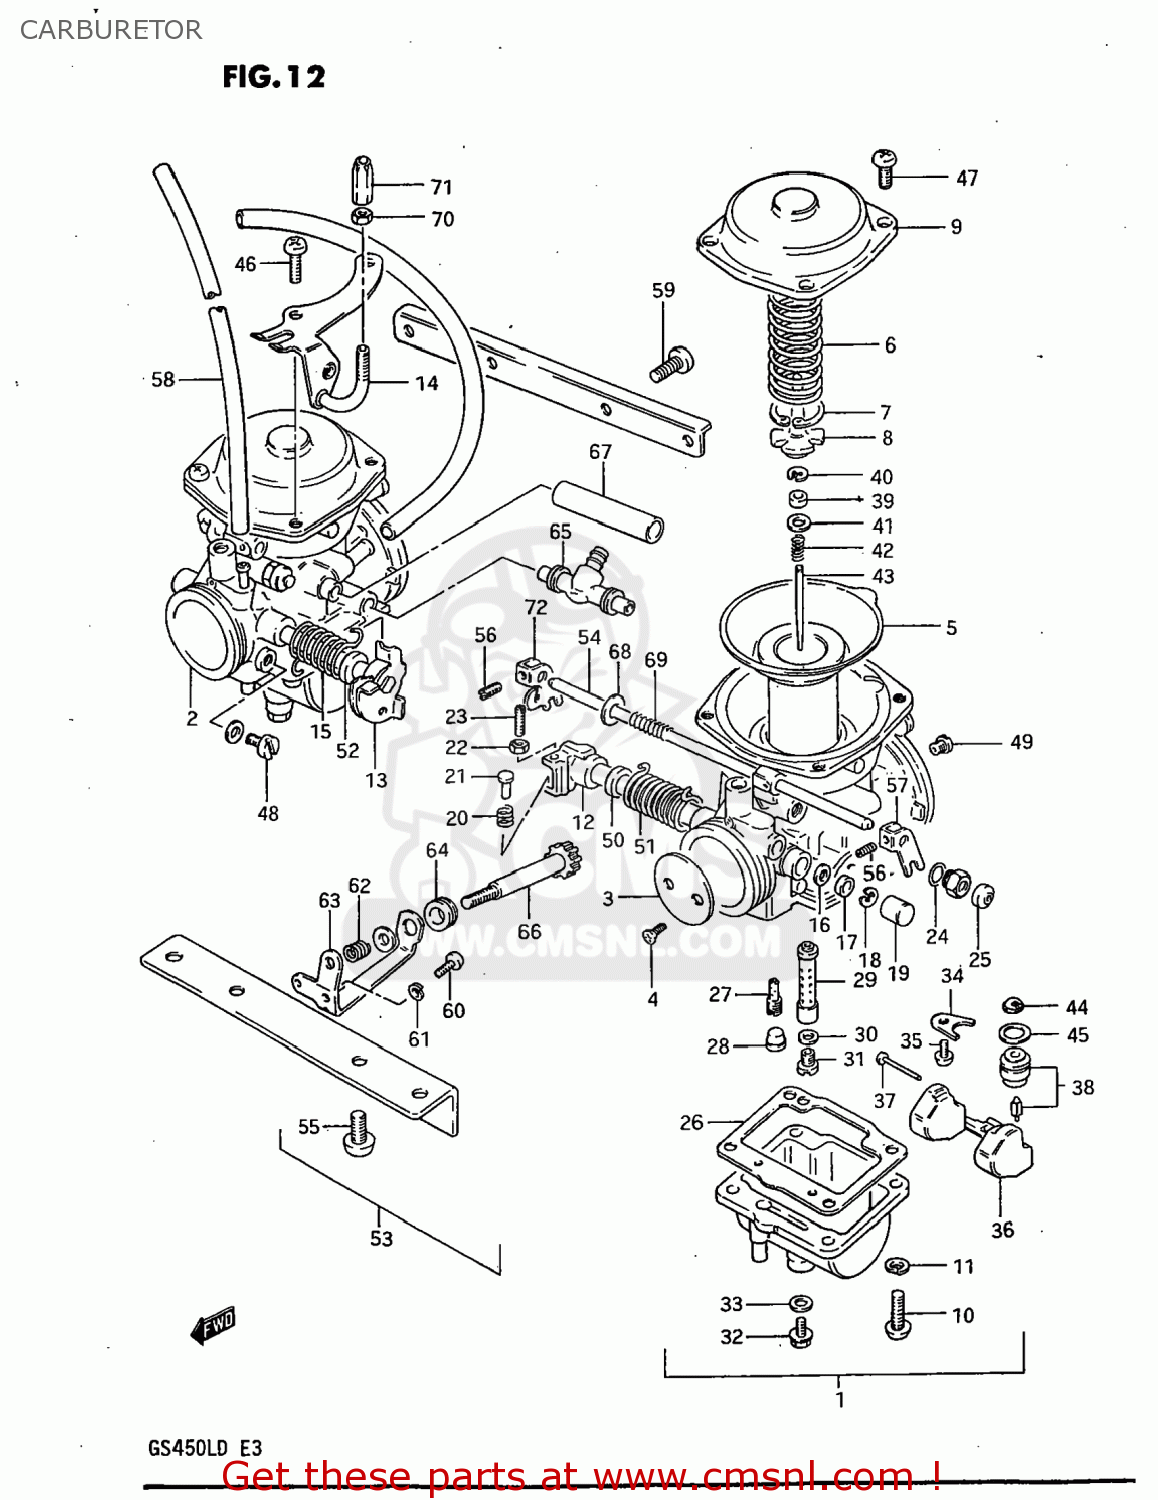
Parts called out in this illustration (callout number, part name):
1	CARBURETOR
2	CARBURETOR ASSEMBLY,RIGHT
3	VALVE,THROTTLE
4	SCREW
5	DIAPHRAGM ASSEMBLY
6	SPRING
7	E RING
8	HOLDER,GUIDE
9	COVER
10	SCREW
11	LOCK WASHER
12	SHAFT ASSEMBLY
13	SHAFT,THROTTLE
14	BRACKET,THROTTLE CABLE
15	SPRING
16	SEAL
17	GASKET,THROTTLE SHAFT (NAS)
18	E RING
19	CAP
20	SPRING
21	PIN,THROTTLE LEVER
22	NUT
23	SCREW
24	O RING
25	CAP,STARTER VALVE
26	GASKET,FLOAT CHAMBER (NAS)
27	JET,PILOT(45)
28	PLUG,NEEDLE JET
29	JET,NEEDLE
30	WASHER,NEEDLE NOZZLE
31	JET,MAIN(115)
32	PLUG,DRAIN
33	GASKET (NAS)
34	PLATE,NEEDLE VALVE FITING
35	SCREW 4X6
36	FLOAT
37	PIN,FLOAT
38	VALVE ASSEMBLY,NEEDLE
39	RING
40	E-RING
41	WASHER,JET NEEDLE
42	SPRING
43	NEEDLE JET
44	FILTER
45	O-RING,NEEDLE VALVE
46	SCREW
47	SCREW
48	SCREW
49	JET,AIR
50	SPACER,THROTTLE SHAFT
51	SPRING
52	SPACER,THROTTLE SHAFT
53	FLANGE ASSEMBLY,CARBURETOR
54	SHAFT,STARTER
55	SCREW 6X12
56	SCREW
57	LEVER
58	HOSE
59	SCREW
60	SCREW
61	LOCK WASHER
62	SPRING,THROTTLE ADJUST
63	BRACKET,THROTTLE ADJUST
64	CAP,RUBBER
65	NIPPLE,CARBURETOR
66	SCREW
67	HOSE
68	WASHER,STARTER PLUNGER
69	SPRING,STARTER
70	NUT
71	ADJUSTER
72	LEVER,STARTER
